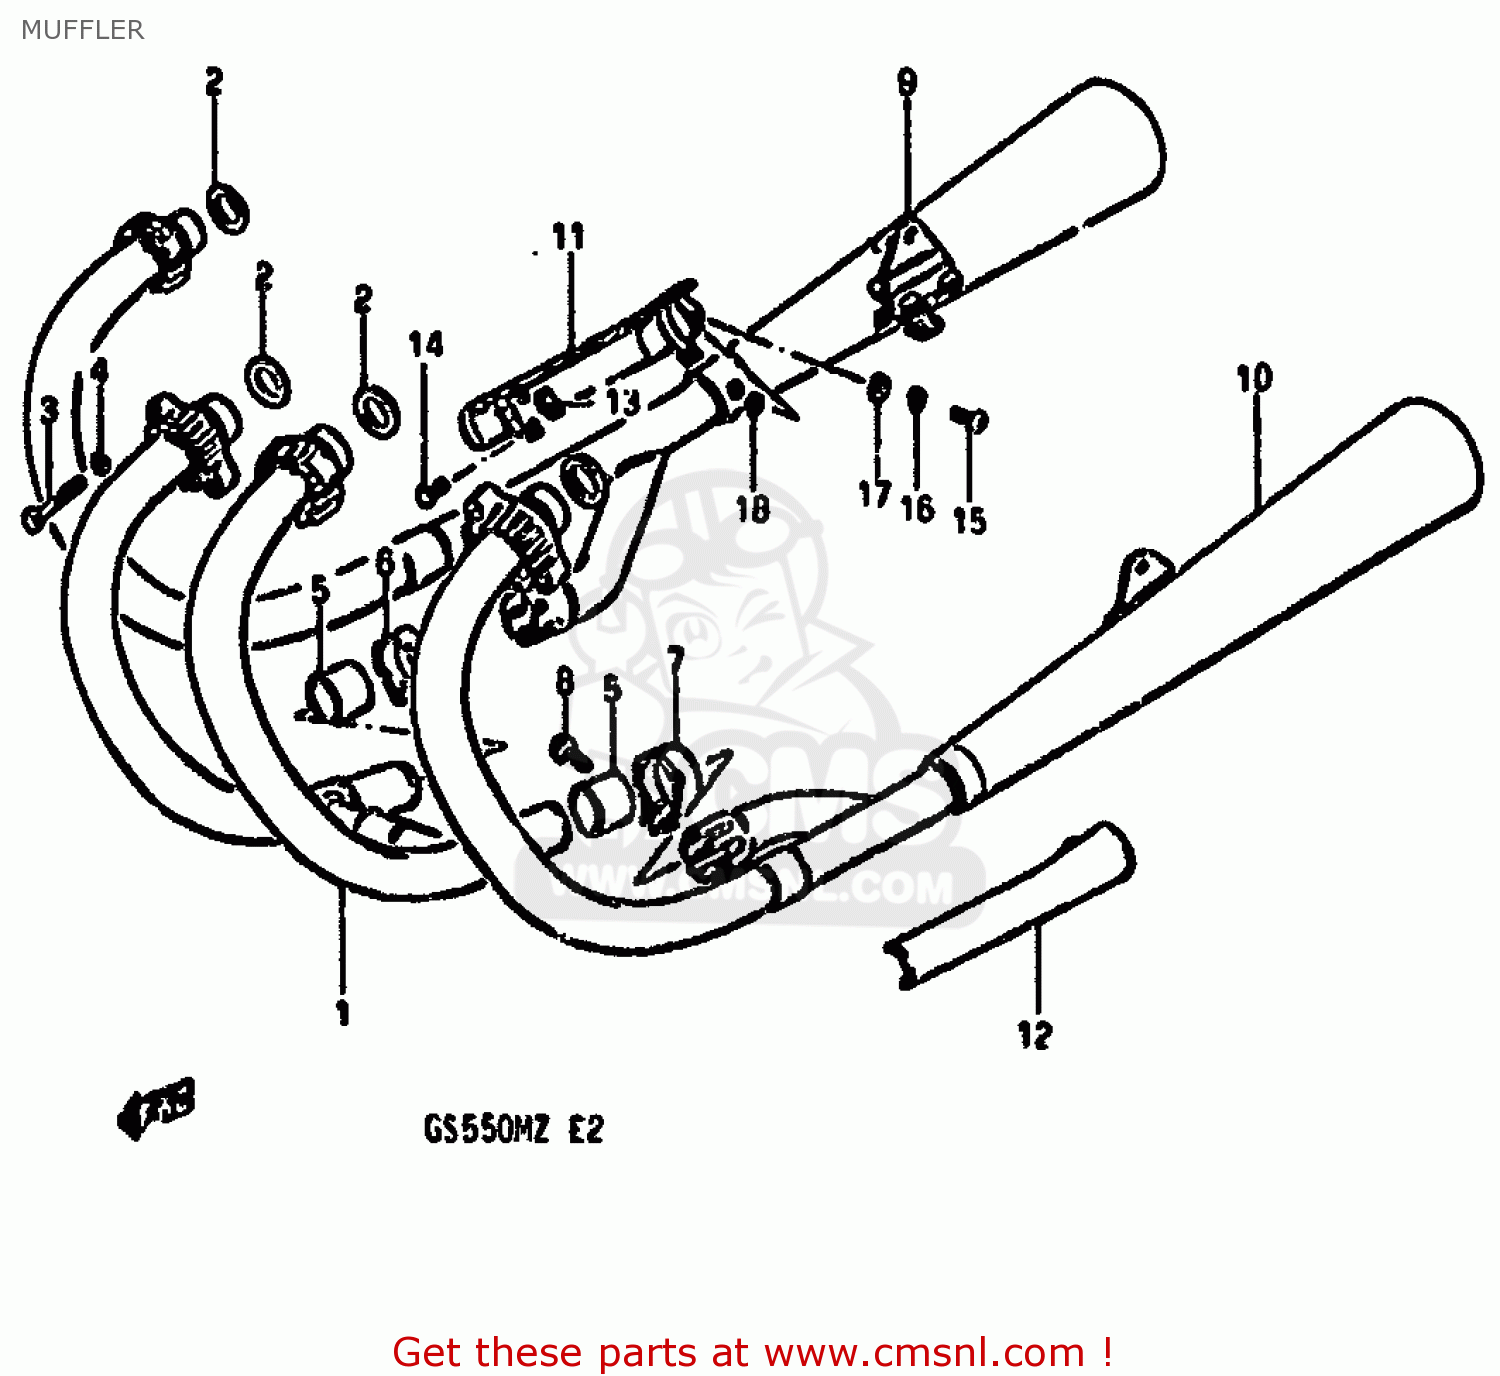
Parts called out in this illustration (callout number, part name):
1	PIPE,EXHAUST,CENTER
2	GASKET,EXHAUST PIPE (NAS)
3	BOLT
4	LOCK WASHER
5	CONNECTOR,MUFFLER
6	CLAMP,MUFFLER CONNECTOR
7	CLAMP,MUFFLER CONNECTOR
8	BOLT
9	MUFFLER,RH
10	MUFFLER,LH
11	COVER,MUFFLER,RIGHT
12	COVER,MUFFLER,LEFT
13	CLAMP,MUFFLER COVER
14	SCREW 5X20
15	SCREW 6X12
16	LOCK WASHER
17	WASHER
18	GASKET 6.2X12X1.5 (MCA)
